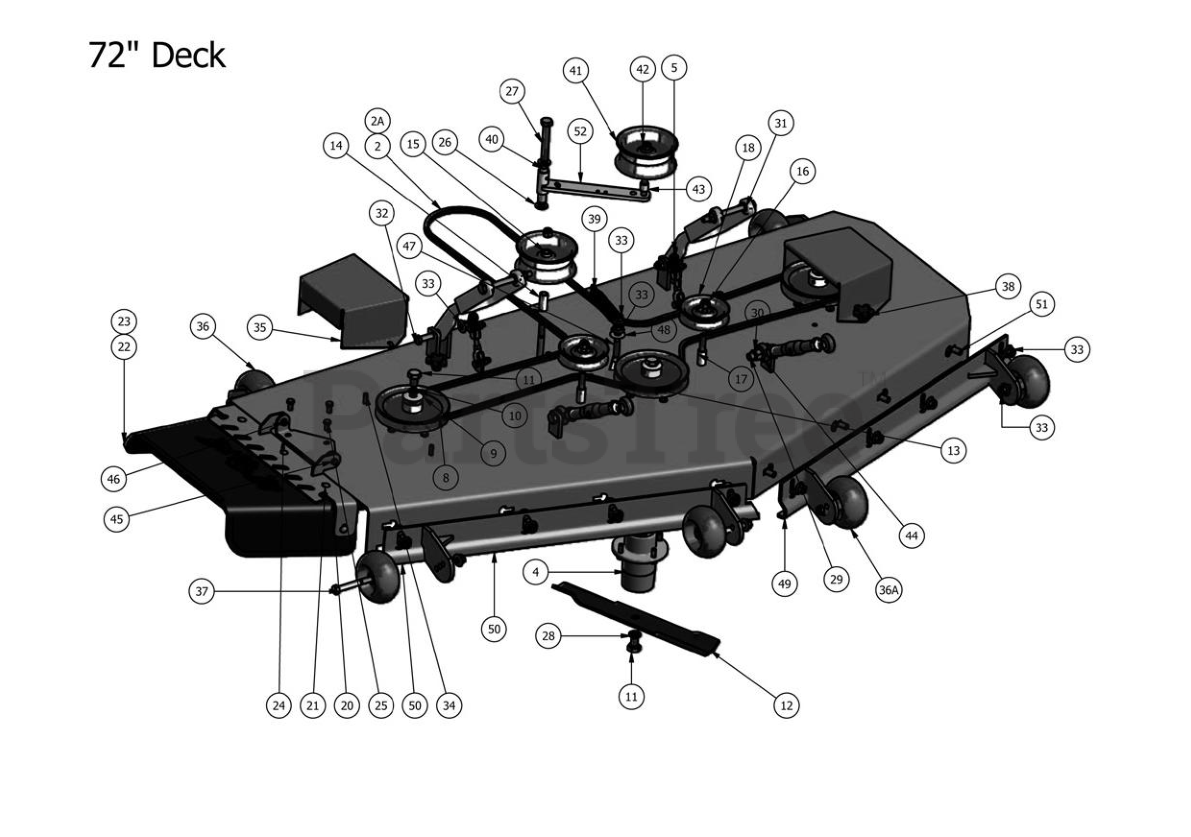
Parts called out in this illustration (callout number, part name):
1	72" Deck Shell
1A	Complete 72" Deck
2	72" Deck Belt (Diesel)
3	4 Link Chain Assembly
4	Double Bearing Spindle
5	3/8" x 1 1/4" Hex Bolt
6	3/8" Lock Washer
7	3/8-16 Hex Nuts Zinc
8	7" Deck Pulley
9	Cup Washer
9A	5/16" Set Screw
10	1/2" Lock Washer
11	5/8" x 1 1/2" Hex Bolt Grade 8
12	72" Fusion High Lift Blade
13	1/2" x 3 1/2" Grade 8 Bolt
14	1 3/4" Pulley Spacer
15	5 3/4" Deck Idler Pulley
16	1/2" Nylock Nut
17	1 1/2" Diesel Pulley Spacer
18	4 3/4" Idler Pulley
19	72" Lower Hanger
20	72" Discharge Chute Upper Hanger Plate
21	5/16" x 1 1/4" Carriage Bolt
22	Rubber Discharge Chute
23	72" Complete Chute Assembly
24	Discharge Chute Hanger (deck mounted)
25	3/8" x 3/4" Hex Bolt
26	.635 ID Plastic Washer
27	5/8" x 4" Hex Bolt
28	5/8" Lock Washer
29	5/8" x 2 1/2" Hex Bolt
30	5/8 Std NC Nylock Nut
31	Deck Arm Assembly
32	1/2" x 2 1/2" Hex Bolt
33	1/2 Nylon Flange Nut-Orange
34	5/16" x 1 1/4" Hex Bolt
35	72" Pulley Cover
36	Anti-Scalp Rollers
36A	Complete Roller Assembly
37	1/2" x 4" Bolt (Grade 8)
38	5/16" Knob
39	Deck Idler Spring
40	5/8 x 1 1/8 Brass Bushing
41	5 3/4" Deck Idler Pulley
42	1/2-13 Nylon Flange Nut-Orange
43	3/4 OD x 1/2 ID x 3\4 Length
44	Turnbuckle (Top Link)
45	5/16" x 1" Hex Bolt
46	5/16" Nylock Flange Nut
47	1/2 x 2" Carriage Bolt
48	1/2" Flat Washer
49	72" Deck Adjustable Front (Left)
50	72" Deck Adustable Front (Right)
51	1/2" x 1 1/4 Carriage Bolt
52	Deck Idler
